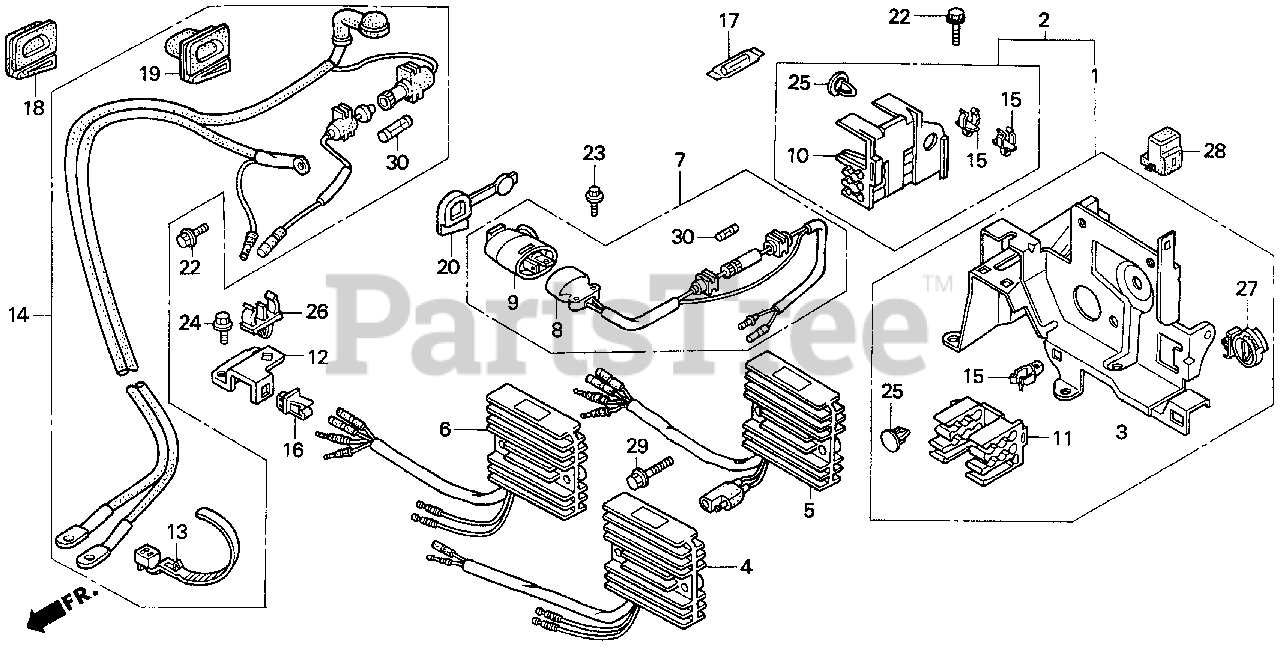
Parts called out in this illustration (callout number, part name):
3	BRACKET, NEUTRAL START CABLE
6	RECTIFIER ASSY., REGULATOR (12A)
10	BRACKET, CONNECTOR (A)
11	BRACKET, CONNECTOR (B)
12	BRACKET, SHIFT CABLE CLIP
13	BAND, WIRE
14	CABLE ASSY., STARTER
15	CLIP, WIRE
16	CLIP B, AIR TEMPERATURE SWITCH WIRE
17	FUSE, SPARE (15A)
19	GROMMET C, OIL CASE
22	BOLT, FLANGE (6X12)
24	BOLT, FLANGE (5X10)
25	CLIP, ANCHOR
26	CLIP, FUEL TUBE
27	CLIP, WIRE HARNESS
28	CAP (090 2P)
29	BOLT, FLANGE (6X20)
30	FUSE A (15A)
